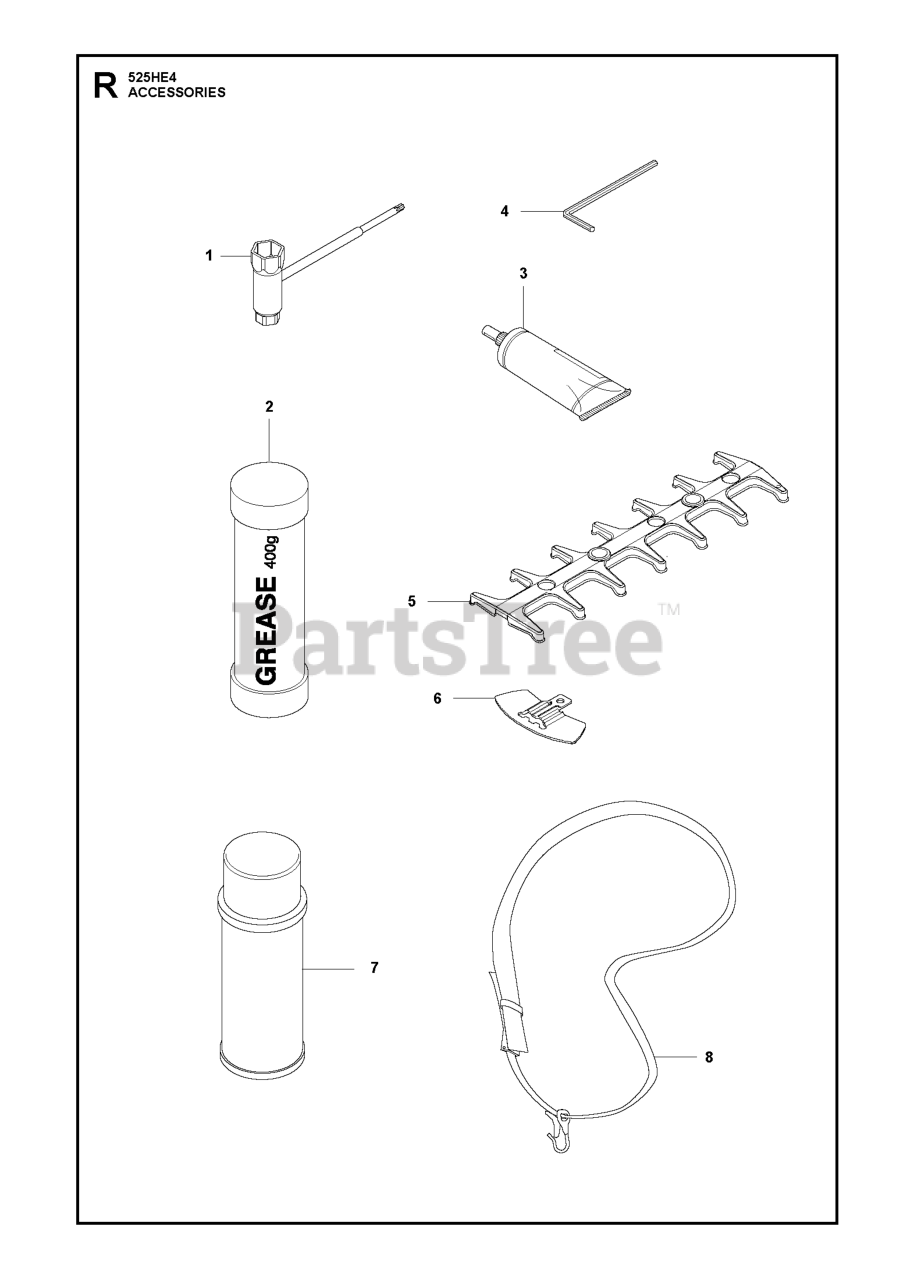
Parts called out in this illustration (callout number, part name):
1	COMBINATION WRENCH TORX
2	HUS MULTI ADVANCE GREASE 400GR
3	GREASE AS ACCESSORY
5	Protection
6	PROTECTION BLADE TIP
8	Harness-w/o warning
